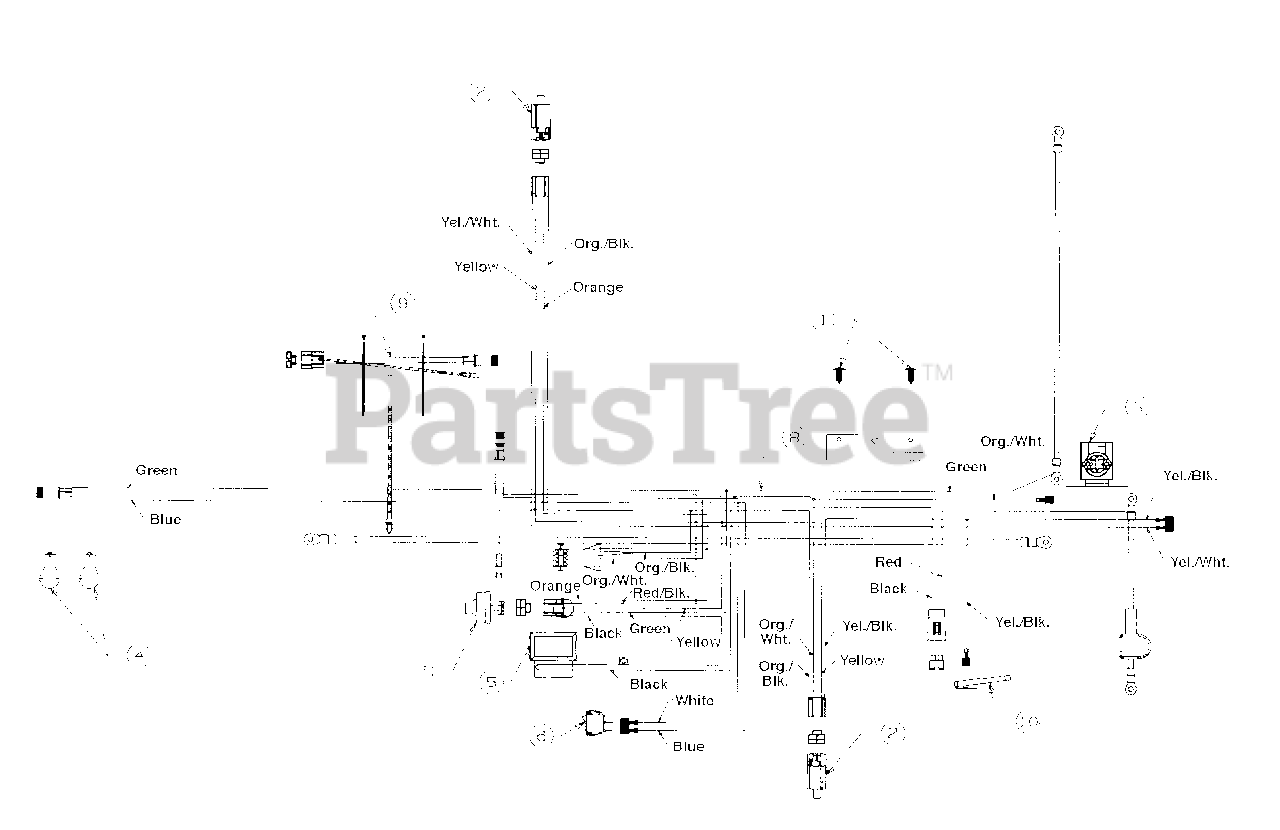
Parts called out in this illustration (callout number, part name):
1	Ratchet
2	Safety Switch
3	Solenoid
4	Bulb (Headlight)
5	Ammeter
6	Light Switch
7	Ignition Switch - 5 Pin
7	Ignition Switch - 6 Pin
8	Wire Harness
9	Wire Harness Adapter
10	Wire Harness (Monitor)
